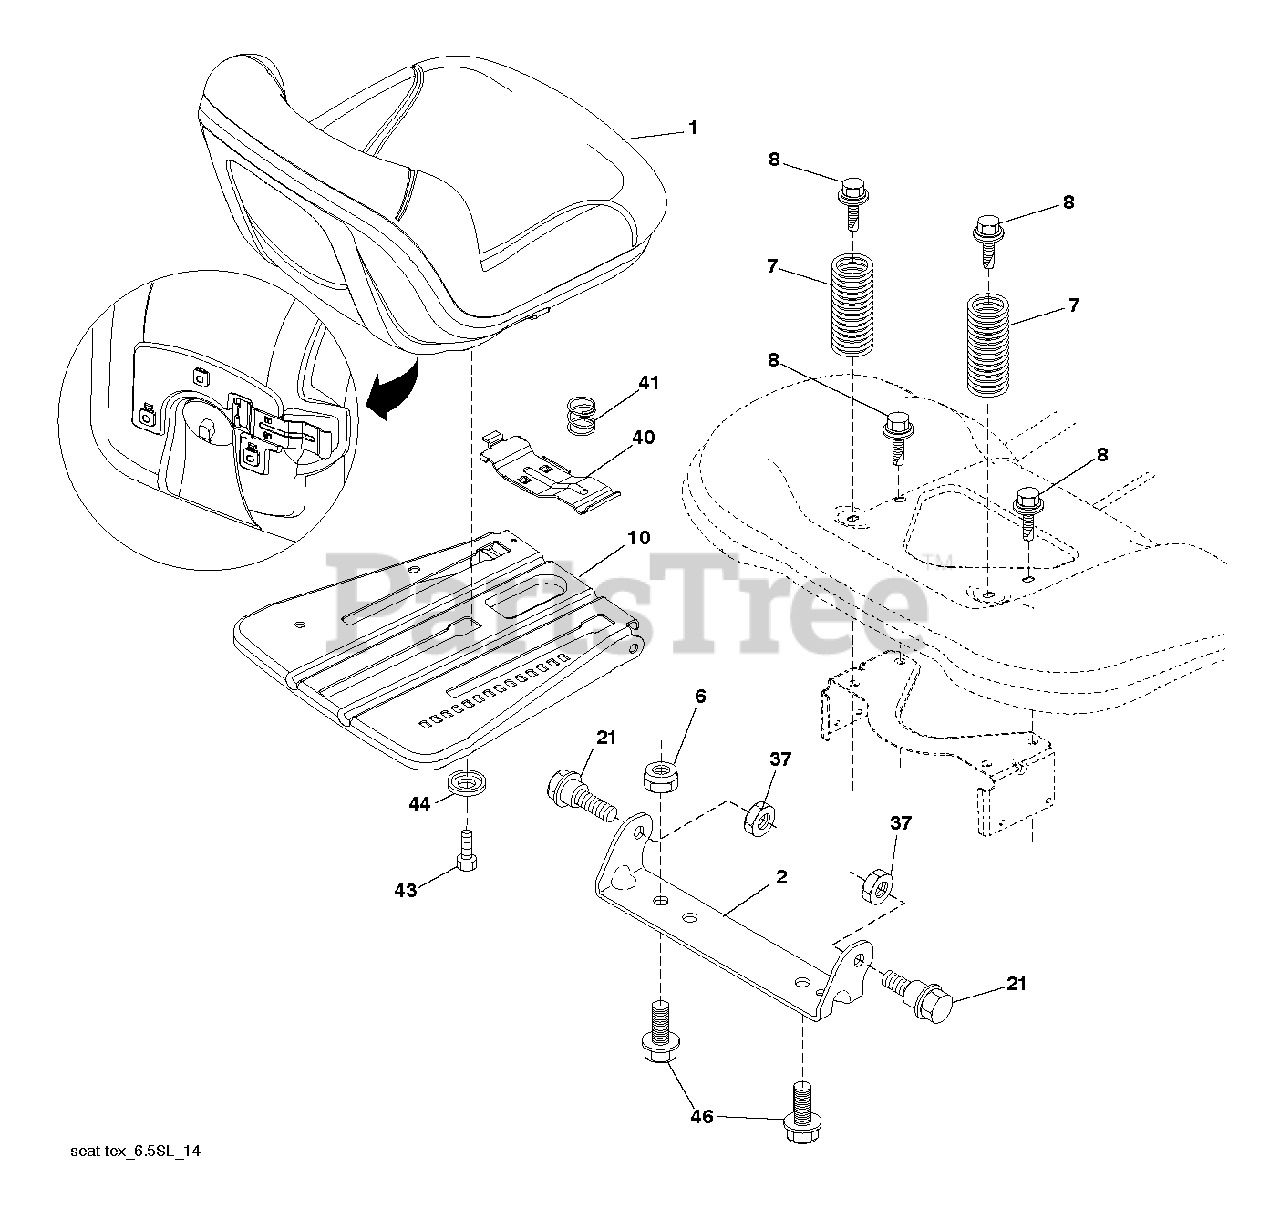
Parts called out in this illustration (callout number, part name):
2	BRKT.PIVOT.FENDER
6	NUT
7	SPRING.COMPRESS.SEAT.
8	BOLT, 5/16-18 X 1 3/4
10	Seat Slide Plate, Pnt
21	BOLT.5/16-18X5/8.SHOULDER
37	NUT.71038.31-18.HEX.NYLOCK
40	HANDLE.SLIDE.SEAT.TEX.BLACK
41	SPRING.LATCH.SEAT.TEX
44	Winged Washer, 38Id 1
46	BOLT.3/8-16X1;1.25OD.WSHR.SEMS
